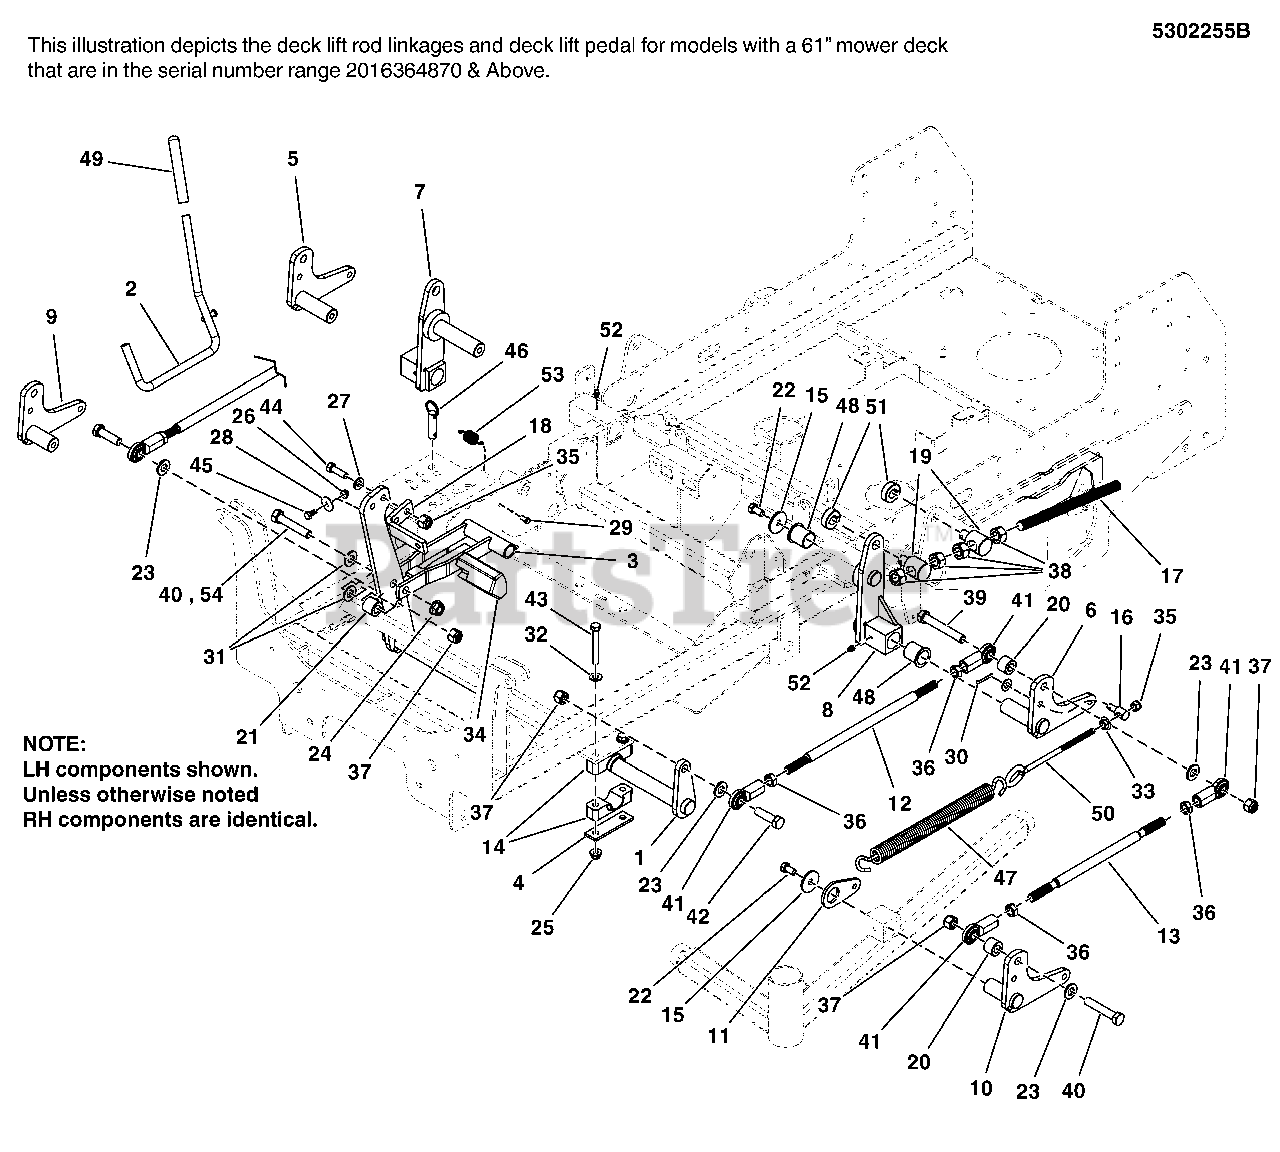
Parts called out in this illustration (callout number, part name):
1	WELD, DECK LIFT SHAFT - ORG
2	WELD, ROD DECK LIFT, IS700 - BLK
4	PLATE, PIVOT BLOCK SUPPORT - BLK
5	WELD, DECK LIFT LEVER, RH - BLK
6	WELD, DECK LIFT LEVER, LH - BLK
7	WELD, REAR LIFT - RH - BLK
8	WELD, REAR LIFT - LH - BLK
9	WELD, DECK LIFT LEVER, RH - ORG
10	WELD, PIVOT DECK LIFT - LH - ORANGE
11	MOUNT, SPRING DECK LIFT - ORANGE
12	ROD, DECK LIFT, 19.25, CZ
13	ROD, 1/2-20 X 20.50", CZ
15	WASHER, .390 X 1.50 X .109, YZ
16	ADJUSTER, DECK HANGER
17	ROD, 5/8-11 X 9.00
18	PEDAL, FOOT - BLK
19	PIVOT, SPRING ROD
20	SPACER, .52 X 1.00 X .75, CZ
21	SPACER, .52 X 1.00 X .88, PM, CZ
22	BOLT, 3/8-16 x 3/4, GD5, YZ WITH PATCH
23	WASHER, 1/2" GR. 9 FLAT
24	NUT, Hex Flange, 1/2-13
25	NUT, 3/8-16, Hex Flange Nylock
26	NUT, 1/4-20, GR5 Flanged Nylock, Zinc/Clear
27	WASHER, 3/8" GR. 9 FLAT
28	WASHER, 1/4
29	PIN, CLEVIS, 1/4 X 1/2, PLATED
30	PIN, COTTER, 1/8" X 3/4
31	WASHER, 1/2
32	WASHER, Flat, 3/8
33	NUT, Hex, Serrated Flange, 3/8-16 (S/N 616 & up)
34	RUBBER, FOOT PEDAL
35	NUT, Hex, Nylon Lock, 3/8-16
36	NUT, Hex Jam, 1/2-20
37	NUT, Hex, Nylon Lock, 1/2-13
38	NUT, Hex, 5/8-11
39	BOLT, 1/2-13 X 3-1/4, HEX HD, GD5, YZ
40	BOLT, 1/2-13 X 2-3/4 GD5 YZ
41	JOINT-BALL .500-20 THD .500ID, CLR ZINC
42	BOLT, 1/2-13 X 1-3/4 GD5 YZ
43	CAPSCREW, Hex Head, 3/8-16 X 2-3/4
44	CAPSCREW, Hex Head, 3/8-16 x 1-1/4
45	CAPSCREW, Hex Head, 1/4-20 x 5/8, GR5
46	PIN, HITCH, 1/2 X 2.00 OAL, YP
47	SPRING-EXT, 1.00 ODX13.25LGX.177WR, BLK
48	BUSHING, 1.00 X 1.13 X 1.38, PLASTIC
49	GRIP, FOAM, .475 X 4.35 X .095
50	EYEBOLT, 3/8-16 X 8, 3 THRD, 1 EYE, CZ
51	COLLAR, 5/8" SPLIT
52	GREASE FITTING, 1/4-28 STRAIGHT
53	SPRING-EXT, .740 ODX2.025LGX.072WR, BLK
54	CAPSCREW, Hex Head, 1/2-13 x 2
